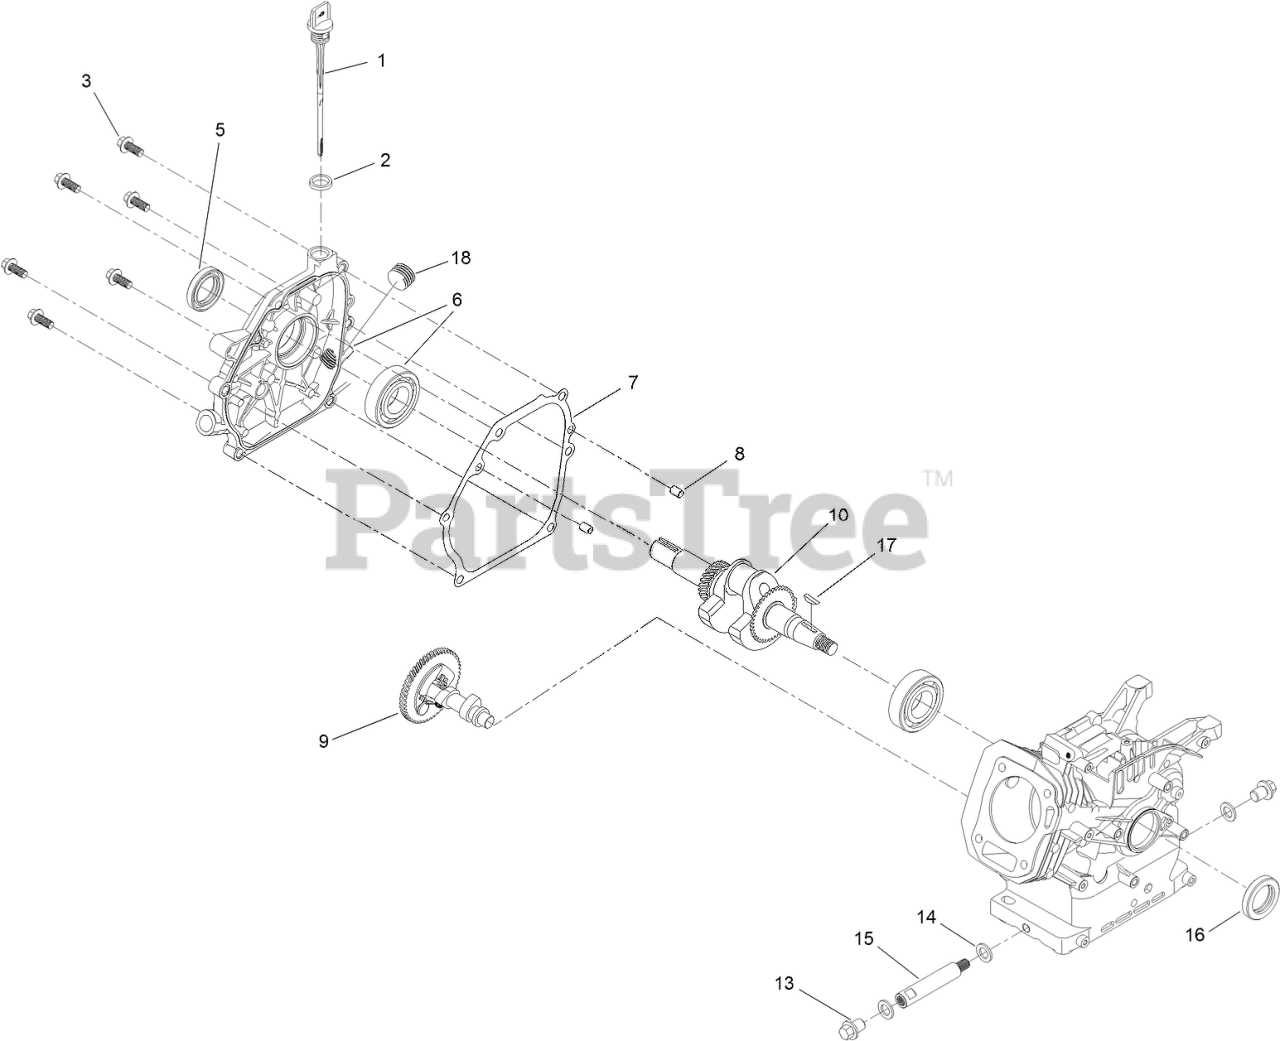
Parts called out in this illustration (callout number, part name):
1	DIPSTICK-OIL
2	GASKET-DIPSTICK, RUBBER
3	SCREW-HHF
5	SEAL-OIL
6	CRANKCASE COVER ASM
7	GASKET-COVER, CRANKCASE
8	PIN-DOWEL
9	CAMSHAFT
10	CRANKSHAFT
13	SCREW-HHF
14	WASHER-PLAIN
15	TUBE-DRAIN, OIL
16	SEAL-OIL
17	KEY-WOODRUFF
18	Plug-Drain
